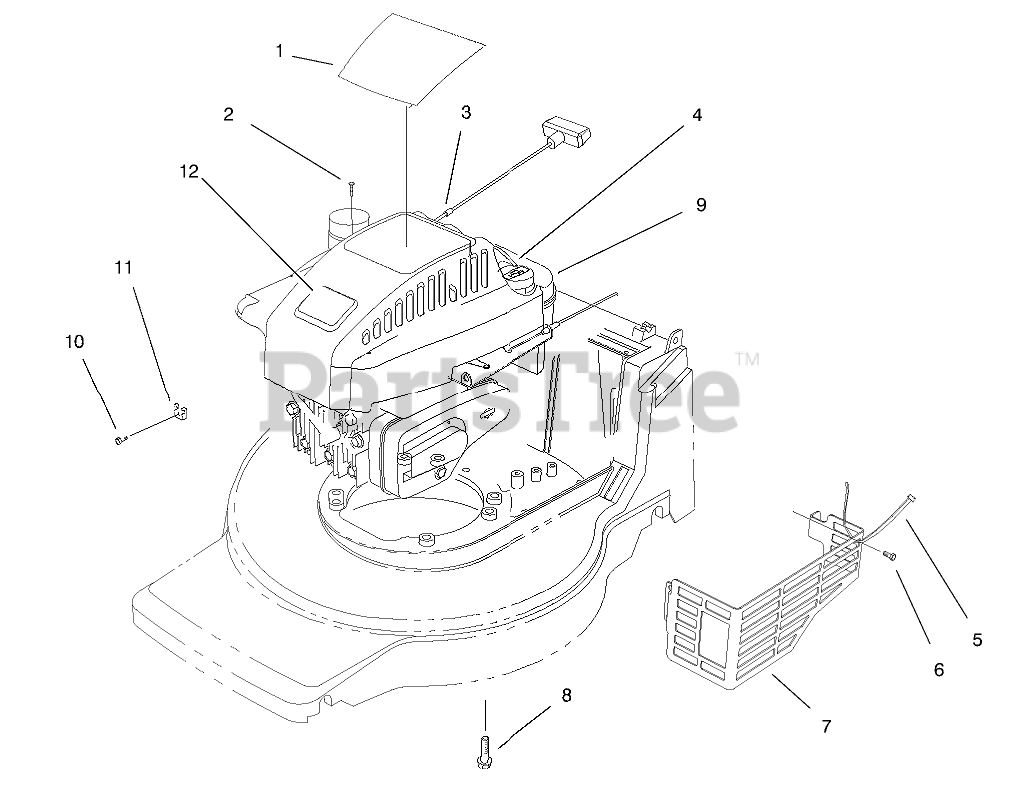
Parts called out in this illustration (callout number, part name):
1	DECAL - RECOIL
2	SCREW-PPH
3	STOP-ROPE
4	SHROUD-ENGINE
5	TIE-CABLE
6	SCREW-HWH
7	SHIELD-MUFFLER
8	SCREW-HWH
10	SCREW-CLAMP
11	CLAMP-CASING
12	PLATE-LOGO
